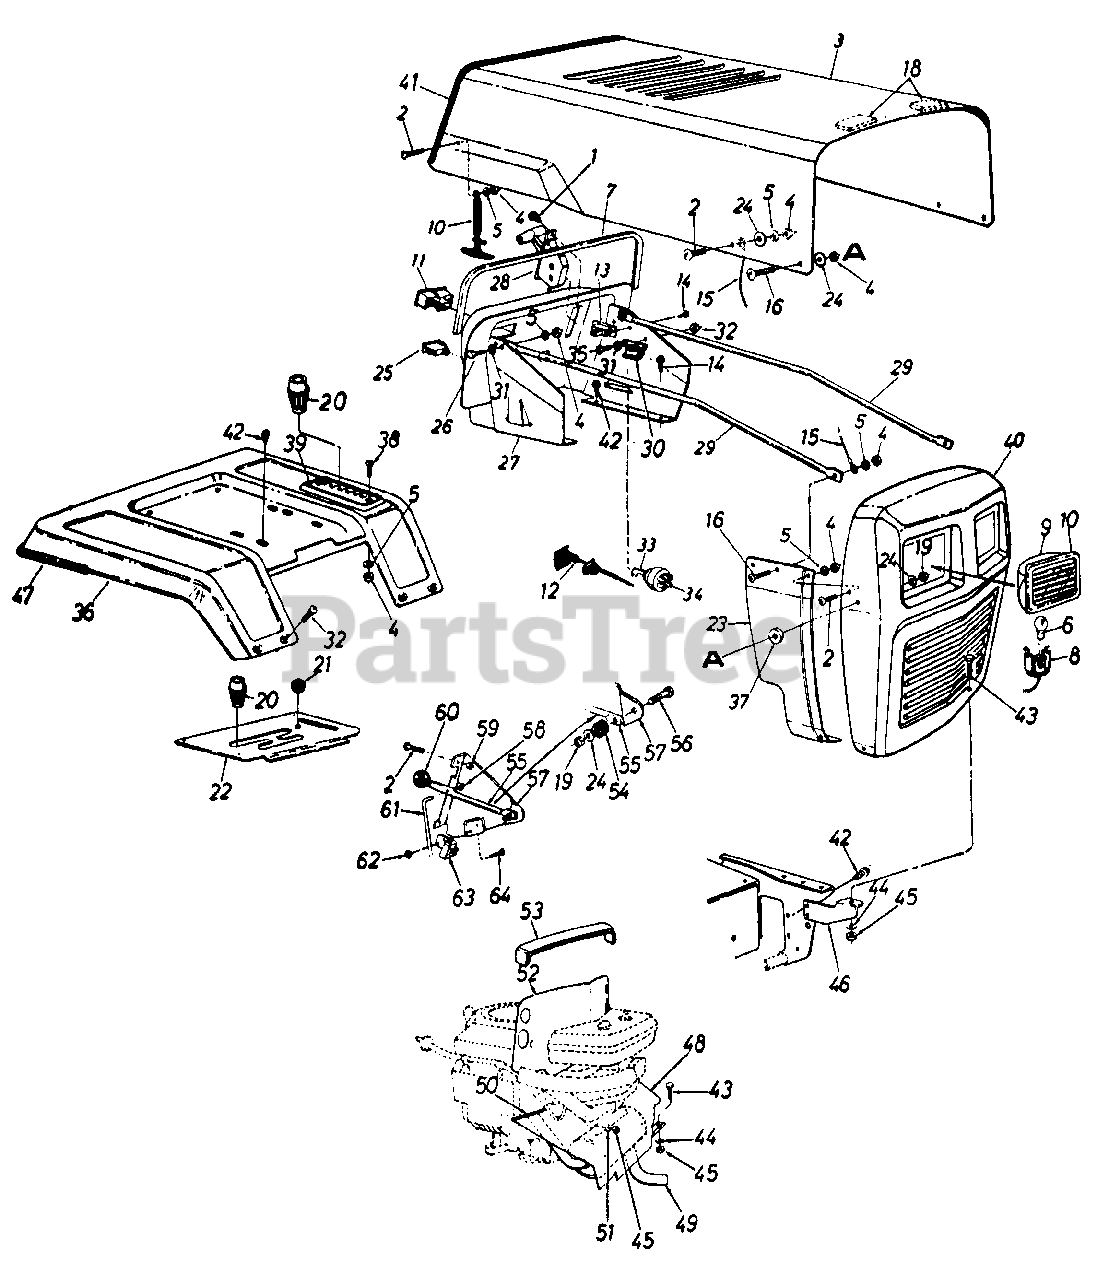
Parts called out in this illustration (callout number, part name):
1	Truss Mach. AB-Tap Scr. #10 x .5" Lg.
2	Truss Mach. Scr. 1/4-20 x .5" Lg.
5	L-Wash. 1/4" I.D.
6	Lamp
7	Trim Strip 29" Lg.
8	Socket
9	Headlight Housing
10	Lens
11	Ammeter
12	Choke Control 46" Lg.
13	Circuit Breaker 8 Amp
14	Hex Tap Scr. #10 x .5" Lg.
15	Hood Stop
16	Truss Mach. Scr. 1/4-20 x .75" Lg.
18	Foam Strip
19	Hex Patch L-Nut 1/4-20 Thd.
20	Shift Knob
21	Ball Knob Brake
22	Transmission Cover
23	Grille Side Panel-R.H.
24	Fl-Wash. .281" I.D. x .73" O.D.
25	Light Switch
26	Truss Mach. Scr. 1/4-20 Thd.
27	Dash Panel Ass'y.
28	Throttle Control Box Ass'y.
29	Grille Support Rod
30	Solenoid
31	Ext. L-Wash. 1/4" I.D.
32	Carriage Bolt 1/4-20 x .5" Lg.
33	Ignition Key
34	Ignition Switch
35	Hex Bolt 1/4-20 x .5" Lg.
36	Rear Fender
37	Rubber Washer
38	Truss Mach. Scr. 1/4-20 x .62" Lg.
39	7-Speed Index Brkt.
42	Hex Wash. AB-Tap Scr. 5/16 x .75" Lg.
43	Hex Bolt 5/16-18 x .75' Lg.
44	L-Wash. 5/16" I.D.
45	Hex Nut 5/16-18 Thd.
46	Grille Mtg. Bracket-R.H.
47	Trim Strip 81" Lg.
48	Front Heat Shield
49	Muffler
50	Trim Strip 10" Lg.
51	Spec. L-Wash. 5/16" I.D.
52	Top Heat Shield
53	PVC Foam
54	Rubber Washer
55	PTO Lever
56	Hex Bolt 1/4-20 x 1.25" Lg
57	Deck Clutch Control Brkt.
58	Push Cap
59	Hex Sems Nut 1/4-20 Thd.
60	Knob-Blade Clutch
61	Deck Control Rod
62	Hex Nut #10-24 Thd
63	Safety Switch
64	Truss Mach. Scr. #10-24 x .5 Lg.
